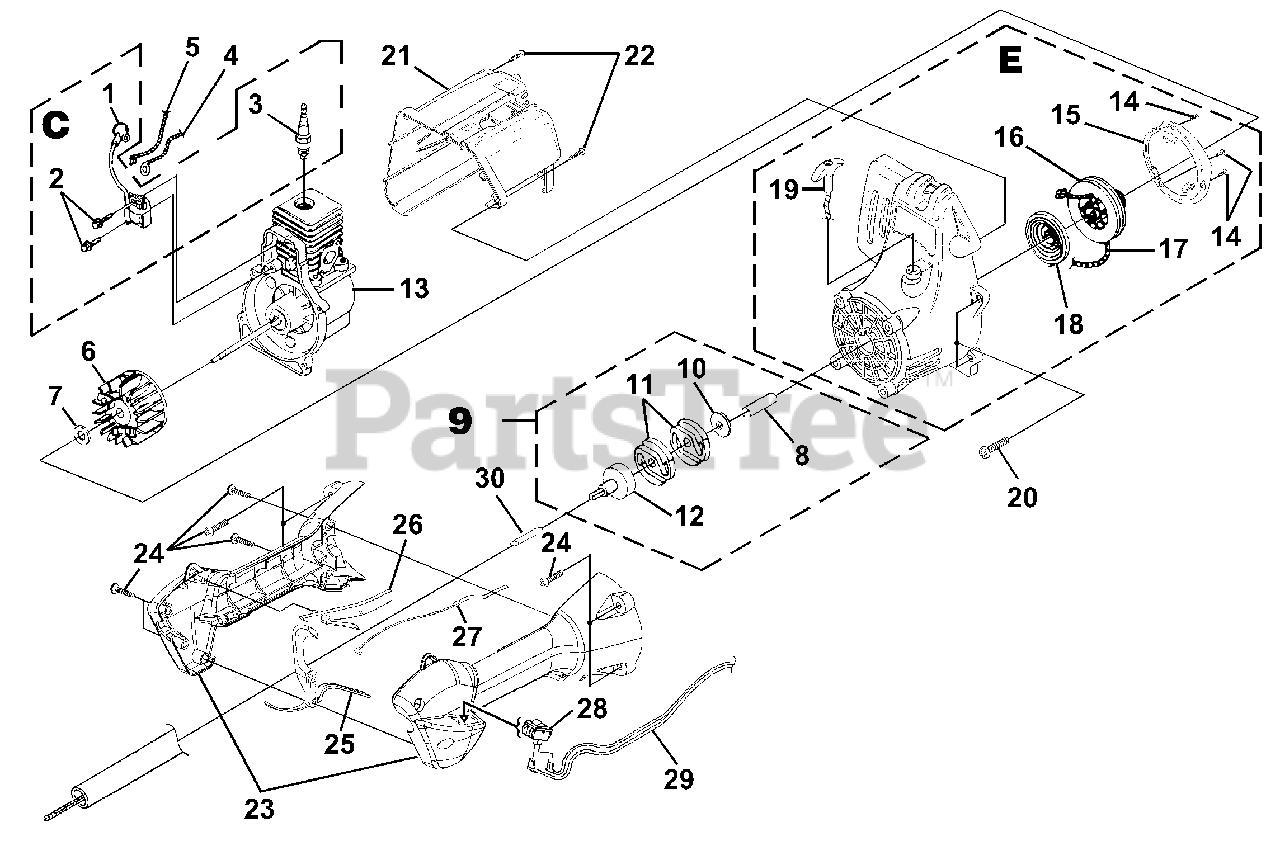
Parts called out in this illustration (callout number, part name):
1	TERMINAL & COVER
2	SCREW-Taptite (8-32 X 1")
3	SPARK PLUG
4	LEAD-Ground
5	LEAD-Electrical
6	ROTOR KIT
7	WASHER-Flat
8	SPACER
9	CLUTCH AND DRUM KIT
10	WASHER-Flat
11	CLUTCH
12	CONNECTOR & DRUM
13	SHORT BLOCK
14	SCREW-Taptite (8-16 X 1/2")
15	BAFFLE-Air
16	PULLEY-Starter
17	ROPE-Starter (42")
18	SPRING & CONTAINER
19	GRIP-Starter
20	SCREW-Taptite (10-24 X 3/4")
21	HOUSING-Rear Kit
22	SCREW-Taptite (10-14 X 7/8")
23	CONTROL HANDLE ASSY.
24	SCREW-Taptite (10-14 X 7/8")
25	TRIGGER-Throttle
26	INTERLOCK-Throttle
27	CABLE-Throttle
28	SWITCH
29	LEAD-Electrical
30	SLEEVE
C	IGNITION KIT
E	COMPLETE STARTER ASSEMBLY
